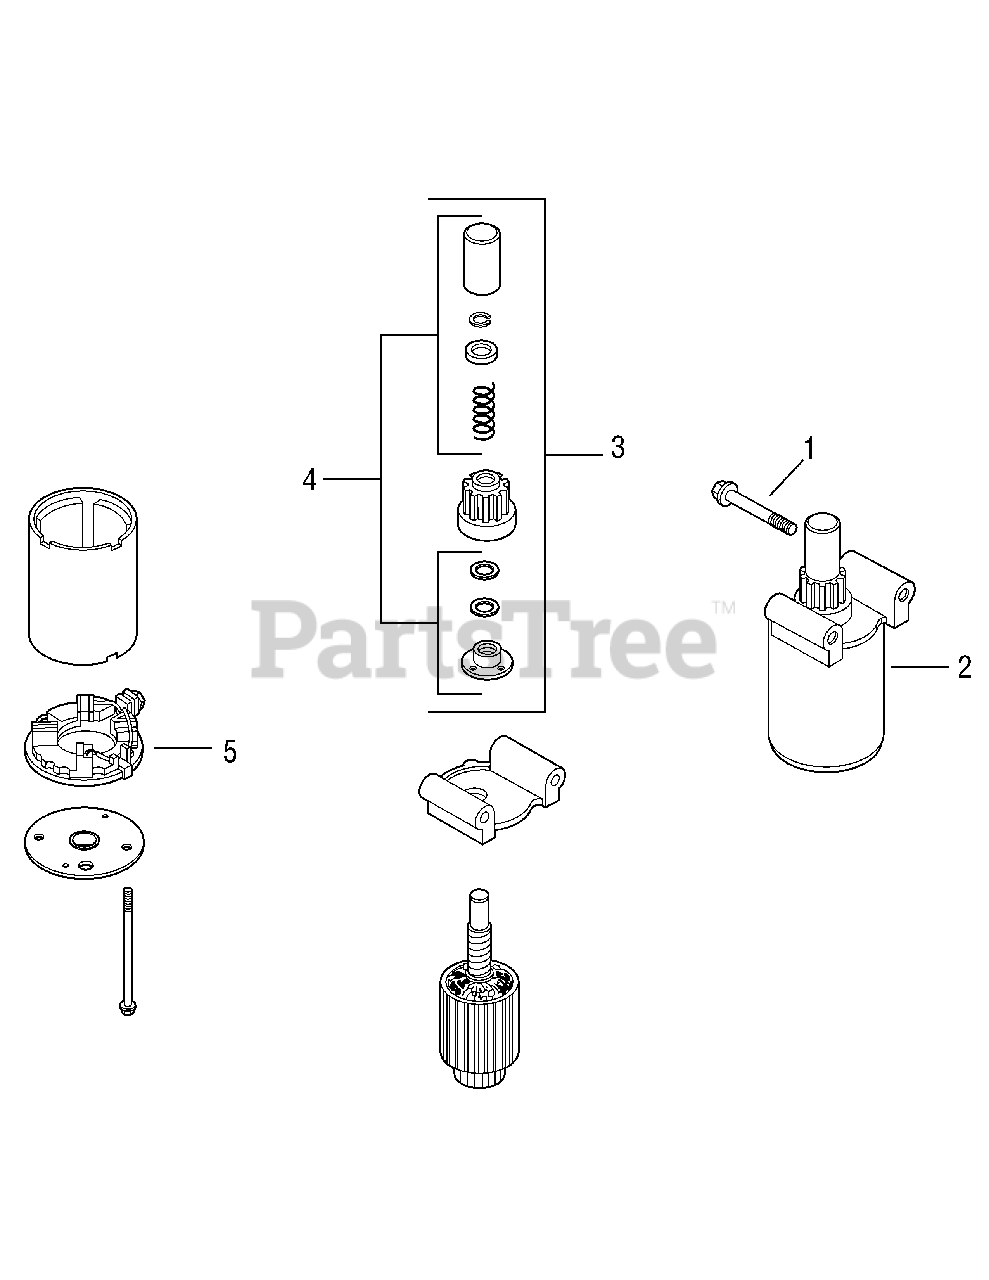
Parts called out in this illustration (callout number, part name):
1	Screw, hex. flange M8x1.25x70
2	Starter assembly (Includes 3-5)
4	Kit, drive parts
5	Commutator, end cap
